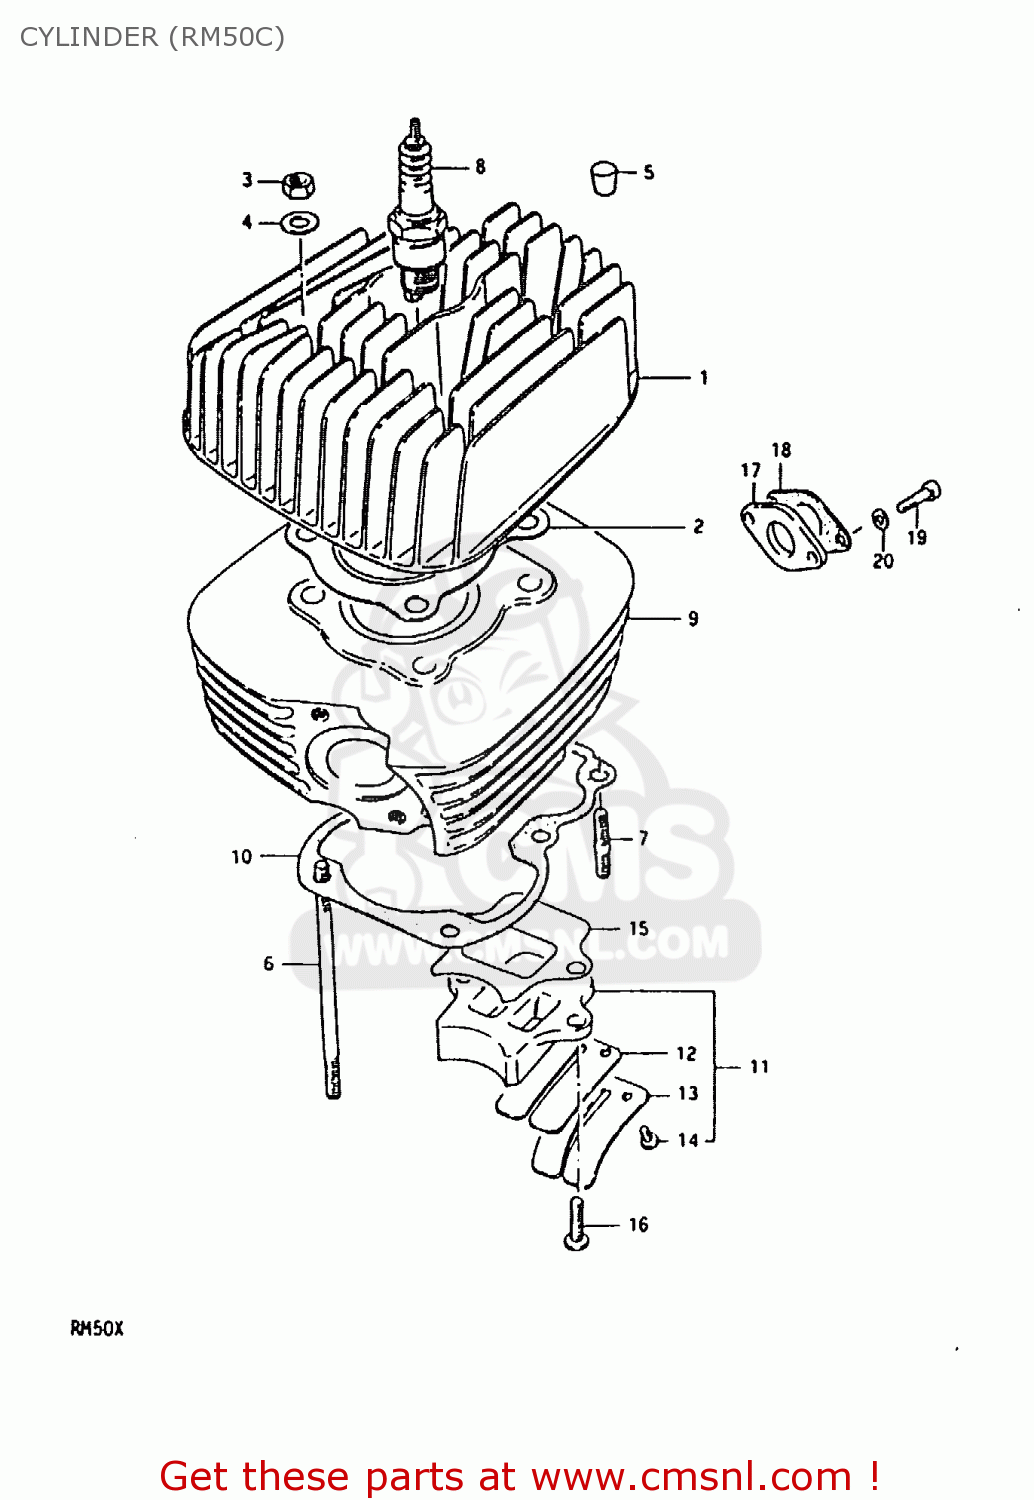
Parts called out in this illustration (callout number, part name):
1	HEAD,CYLINDER
2	GASKET,CYLINDER HEAD (NAS)
3	NUT
4	WASHER
5	PAD,CYLINDER HEAD
6	BOLT,STUD
7	STUD 6X16
8	SPARK PLUG
9	CYLINDER
10	GASKET,CYLINDER (MCA)
11	VALVE ASSEMBLY,REED
12	STOPPER,REED VALVE
13	VALVE,REED
14	SCREW,REED VALVE
15	GASKET,REED VALVE (MCA)
16	SCREW
17	INSULATOR,CARBURETOR
18	GASKET,CARBURETOR (MCA)
19	BOLT
20	WASHER
